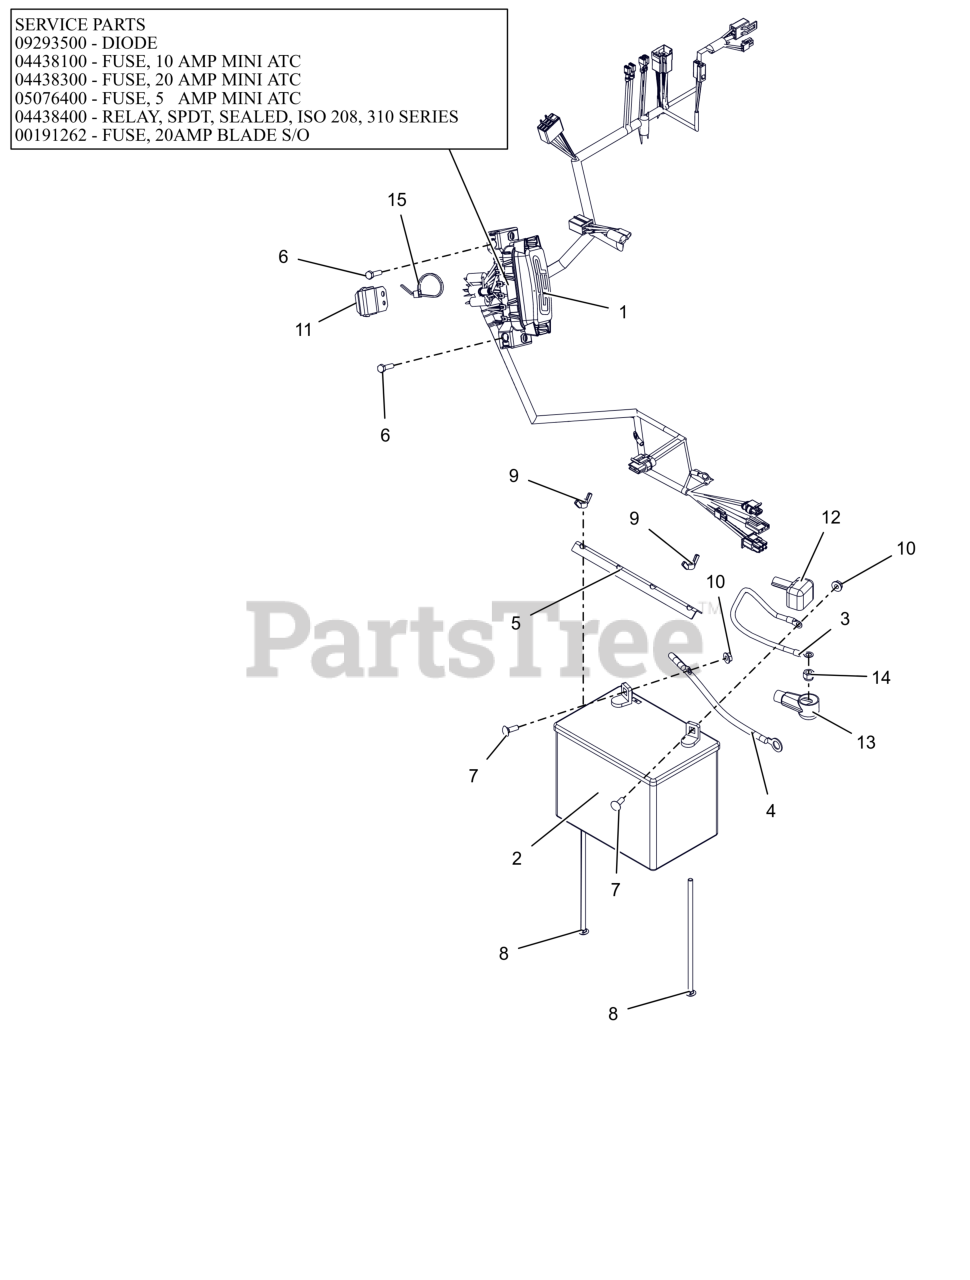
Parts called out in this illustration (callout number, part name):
1	HARNESS, PROSTANCE
1	DIODE, CONNECTOR SHELL
1	FUSE,10 AMP MINI-ATC
1	FUSE,20 AMP MINI ATC
1	FUSE, 5 AMP MINI-ATC
1	RELAY,MICRO5 TERML W/RESISTOR
1	FUSE, 20 AMP BLADE S/O
2	BATTERY, 300 CCA 10U1L
3	CABLE, STARTER 13.00"
4	CABLE-GROUND .25 X 13.00 X .31
5	HOLD DOWN
6	BLT, HEX M6-1.0 X 25 G8.8 ZCC
7	BLT, RHSN .25-20X.750 G5 ZCC
8	BTL,RHSN .250-20 X 7.5 G5 ZCC
9	NUT, LK-WING .25-20 ZCC
10	NUT-SPNLK-FLG .25-20 ZC120
11	MODULE,INTERLOCK,DELAY, 1801
12	INSULATOR
13	BOOT, BATTERY TERMINAL-RED
14	NUT,NYL M8-1.25 G8.8 ZCC
15	CABLE TIE, .15 X 8.50
